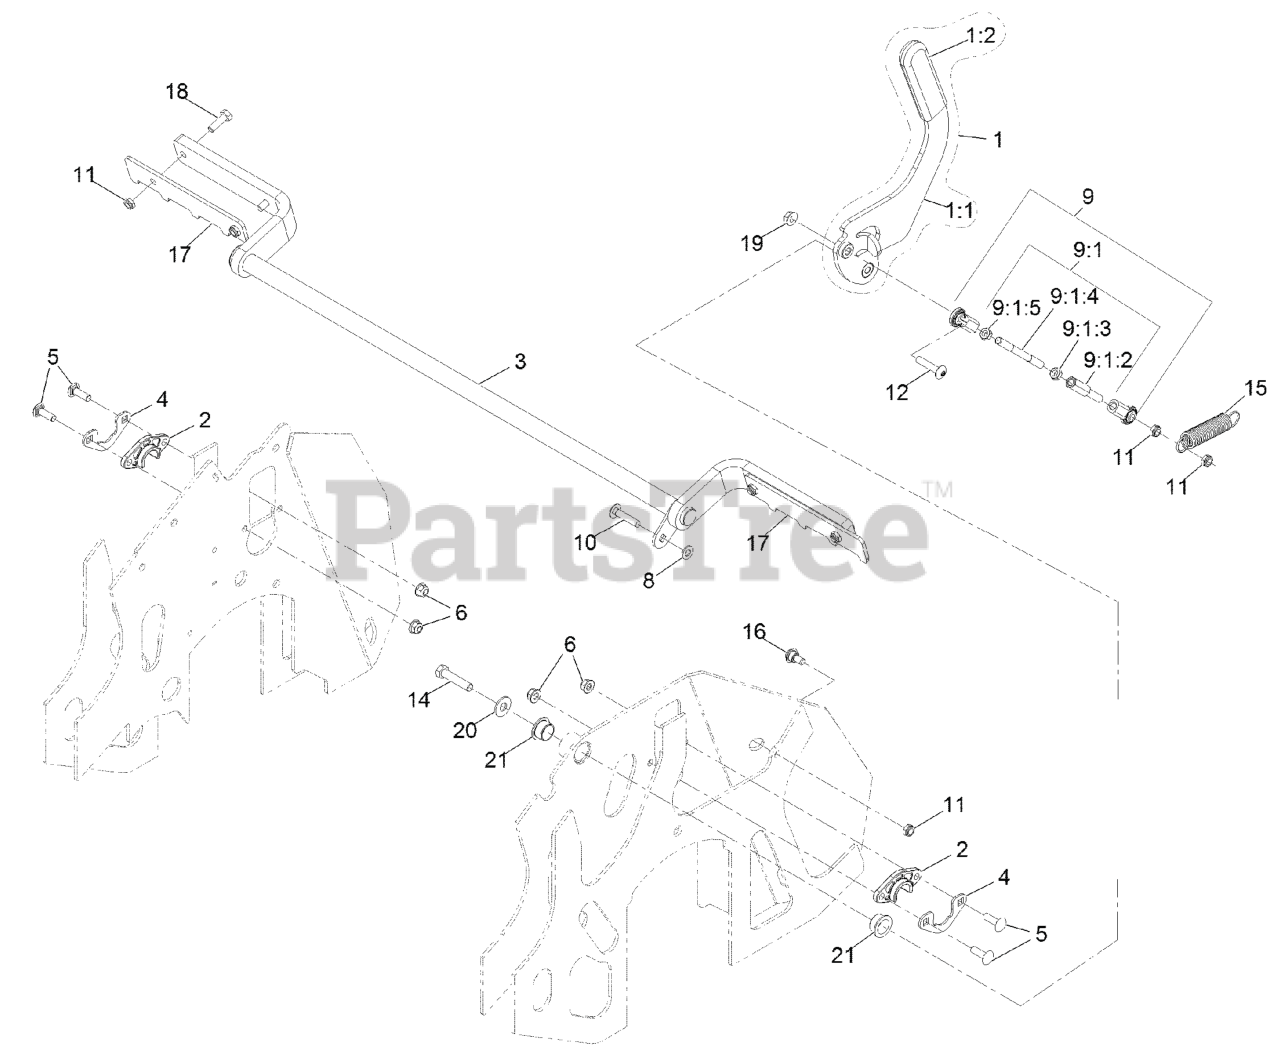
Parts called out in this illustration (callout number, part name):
1:1	WELD, BRAKE LEVER
1:2	GRIP-LEVER
2	BUSHING-FLANGE
4	SUPPORT, BEARING
5	SCREW-CARR
6	NUT-HF, NI
8	WASHER-PLAIN
9	ASM, LINKAGE
9:1	ASM, Motion Control Link
9:1:2	ROD-ADJUSTMENT
9:1:3	NUT-HEX JAM, LH
9:1:5	NUT-HJ
10	BOLT-CARR
11	NUT-LOCK, NI
12	SCREW-TORX
14	SCREW-HH
15	SPRING-IDLER
16	BOLT-SHOULDER
17	PLATE, SNUBBER
18	SCREW-HH
20	WASHER-FLAT
21	BUSHING, IGUS
